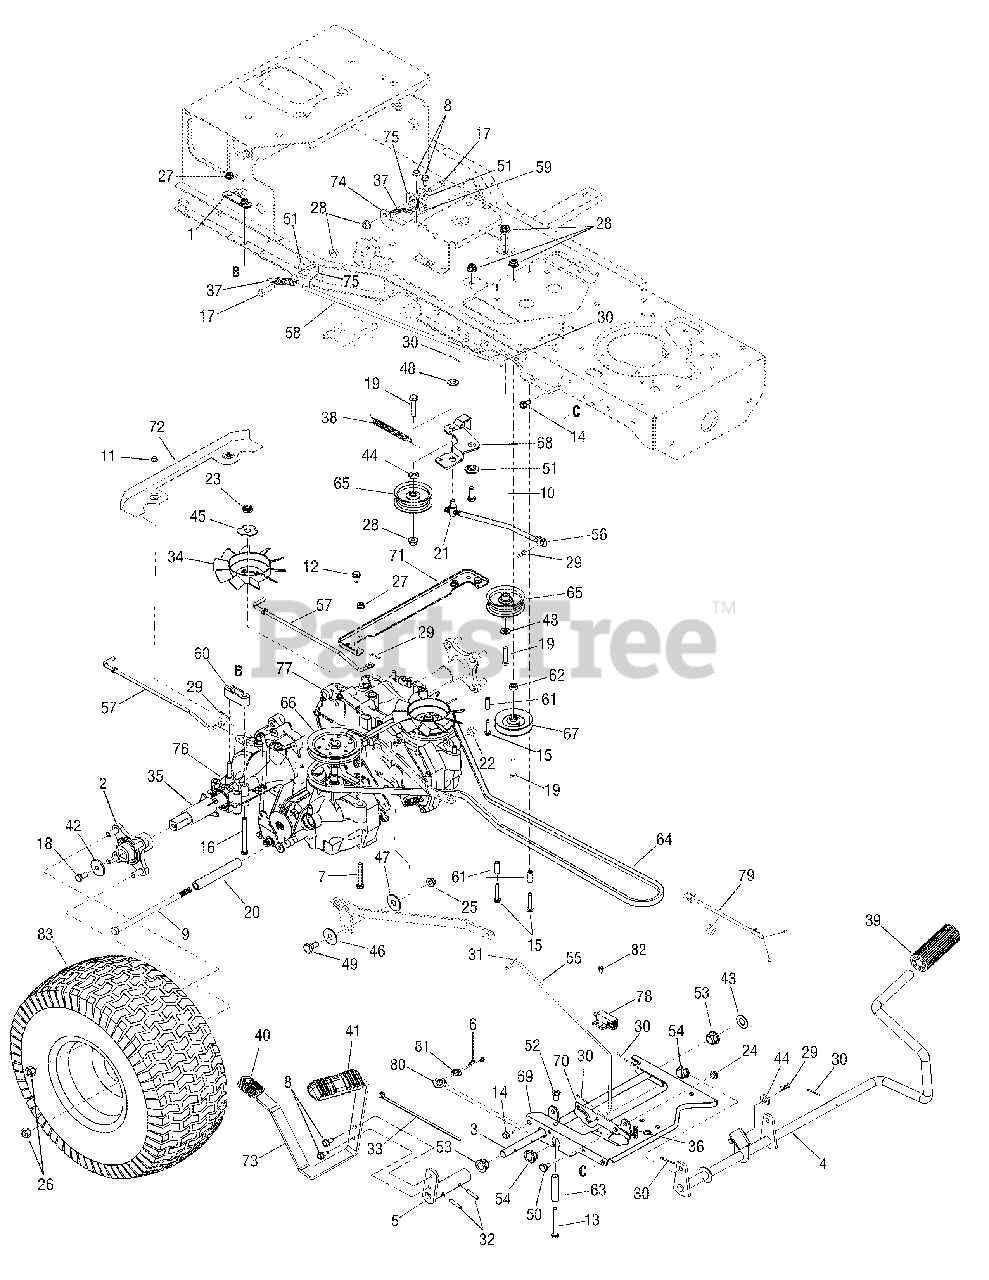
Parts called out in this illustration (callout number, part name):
2	Hub, Wheel
3	Shaft Assembly, Hydro Control Pedal
4	Shaft Assembly, Brake Control
7	Screw, Hex Cap, 5/16-18 x 2.25 Gr5
8	Screw, Hex Wash Hd. Tapp, 5/16-12 x .75
9	Screw, Hex Cap, 7/16-14 x 8.5 Gr5
10	Screw, Hex Cap, 3/8-16 x 1.0 Gr5
11	Screw, Hex Wash. Hd. Tapp, 1/4-20 x .5
12	Screw, Hex Wash Hd. Tapp, 5/16-18 x .5
13	Screw, Hex Cap, 1/4-20 x 2.25 Gr5
14	Screw, Hex Wash Hd. Tapp, 5/16-12 x .75
15	Screw, Hex Wash Hd. Tapp, 1/4-20 x .75
16	Screw, Hex Cap, 5/16-18 x 3.5 Gr5
17	Screw, Hex Cap, 3/8-16 x 1.25 Gr5
18	Screw, Hex Cap Lock, 3/8-16 x .75 Gr5
19	Screw, Hex Cap, 3/8-16 x 2.0 Gr5
20	Spacer, .479 x .75 x 4.97
21	Ferrule, 3/8-24 x .375 Dia.
22	Nut, Hex Lock, 7/16-14 GrA
23	Nut, Hex Jam Insert Lock, 1/2-20 Gr5
24	Nut, Hex Flange Lock, 5/16-18 Gr5
25	Nut, Hex Lock, 3/8-16
26	Nut, Lug, 7/16-14
27	Nut, Hex Flange Insert Lock, 5/16-18 GrF
28	Nut, Hex Flange Insert Lock, 3/8-16 GrF
29	Pin, Internal Cotter
30	Pin, Cotter, 3/32 x 1/0
31	Pin, Bowtie Cotter
32	Pin, Spirol, .25 x 1.25
33	Tie, Cable
34	Fan, Hydro
35	Sleeve, 1.015 x 2.6
36	Spring, Compression, .405 x 1.17
37	Spring, Extension, .59 x 5.4
38	Spring, Extension, .60 x 6.44
39	Pad, Foot, 4.0 in. Lg
40	Pad, Reverse Pedal
41	Pad, Forward Pedal
42	Washer, Flat, .39 x 1.5 x .134
43	Washer, Flat, .625 x 1.0 x .067 HT
44	Washer, Flat, .407 x .812 x .135 HT
45	Washer, Hydro Lock
46	Washer, Flat, .531 x 1.75 x.09
47	Washer, Flat, .406 x 1.5 x.105
48	Washer, Flat, .406 x .812 x .051
49	Bolt, Shoulder, .496 x .336:3/8-16
50	Bolt, Shoulder, .435 x .160:5/16-18
51	Spacer, Shoulder, .625 ID x .169
52	Nut, Shoulder, .375 Dia x .5
53	Bearing, Hex Flange
54	Bearing, Hex Flange, .625 ID Split
55	Rod, Park Brake
56	Rod, Drive Engage
57	Rod, Hydro Bypass
58	Rod, Brake RH
59	Rod, Brake LH
60	Spacer, T-Axle
61	Spacer, .26 x .372 x 1.42
62	Spacer, .38 x .625 x .265
63	Spacer, .375 x .5 x 2.0
64	V-Belt, 88.4
65	Pulley, Flat Idler, 2.75
66	Pulley, V Type, 4.5
67	Pulley, V Type Idler, 3.06
73	Pedal, Hydro Drive
77	Transmission, Hydro LH
78	Switch, Interlock (Brake)
79	Harness, Reverse Jumper
80	Switch, Reverse
81	Plate, Insulator Nut
82	Screw, Shoulder, #10-32 : .5
